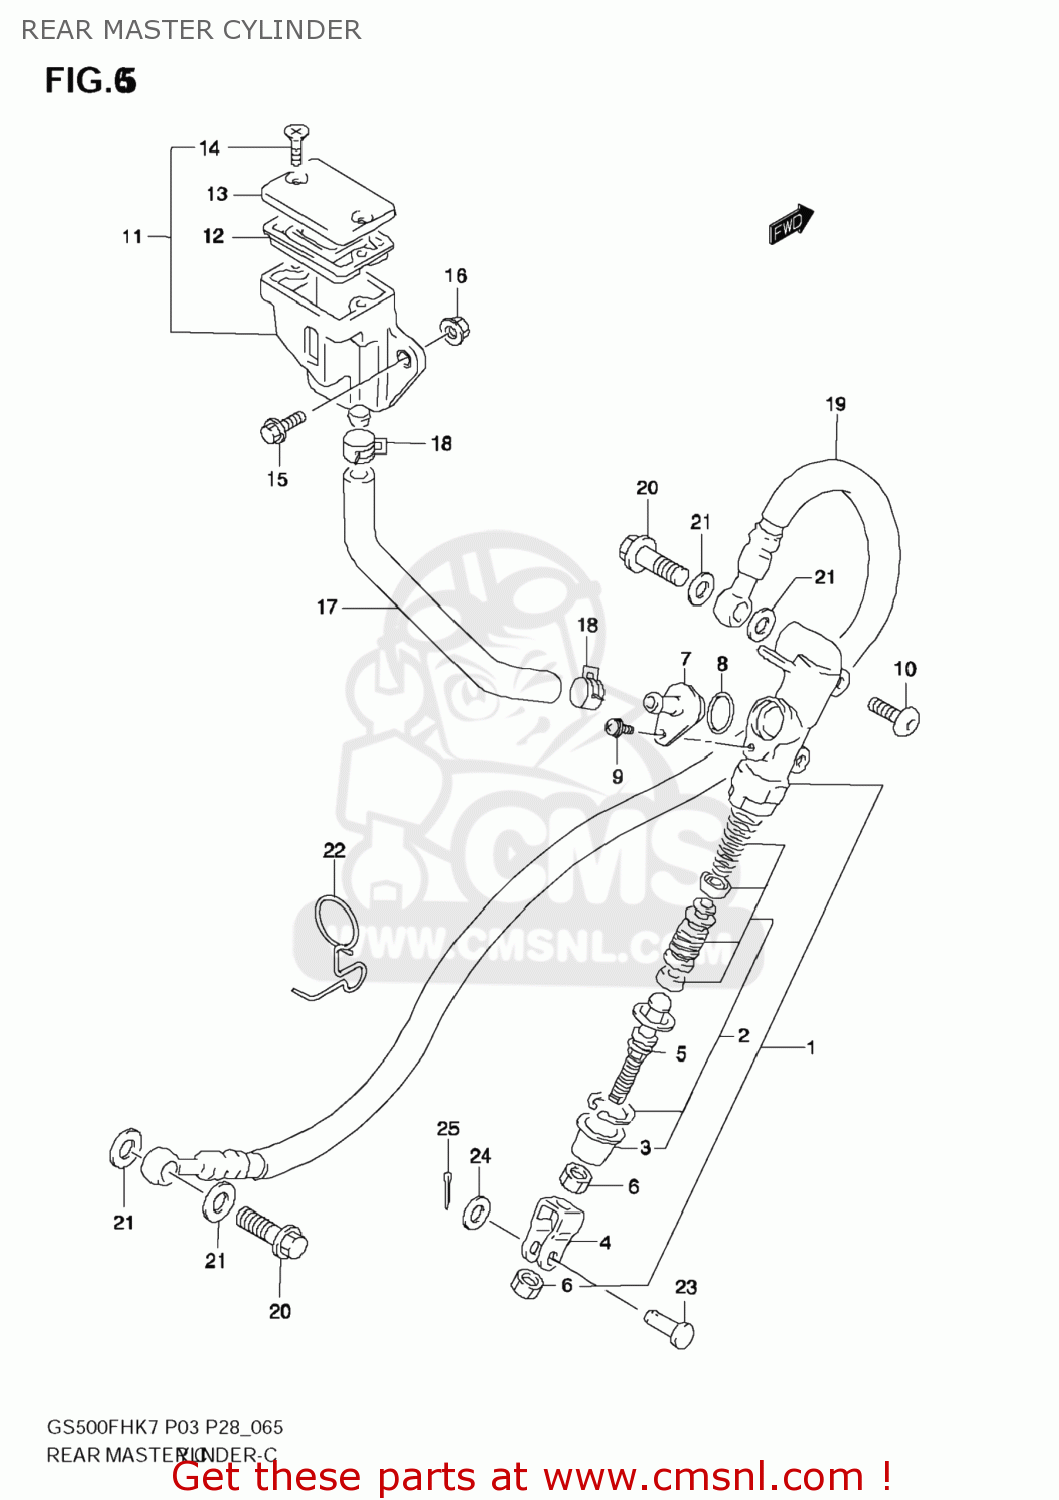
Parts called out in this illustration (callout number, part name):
1	CYLINDER ASS R
2	PISTON/CAP SET
3	BOOT
4	YOKE
5	ROD, PUSH
6	NUT
7	CONNECTOR
8	O-RING
9	SCREW
10	SCREW(6X25)
11	TANK ASSY REAR
12	DIAPHRAGM
13	CAP
14	SCREW
15	BOLT UH125&200
16	NUT
17	HOSE,RESERVOIR TANK
18	CLIP
19	HOSE,RR BRAKE
20	BOLT UNION
21	WASHER(10X15X1.5)
22	GUIDE,RR BRAKE HOSE
23	PIN
24	WASHER GS500/K
25	PIN, COTTER
